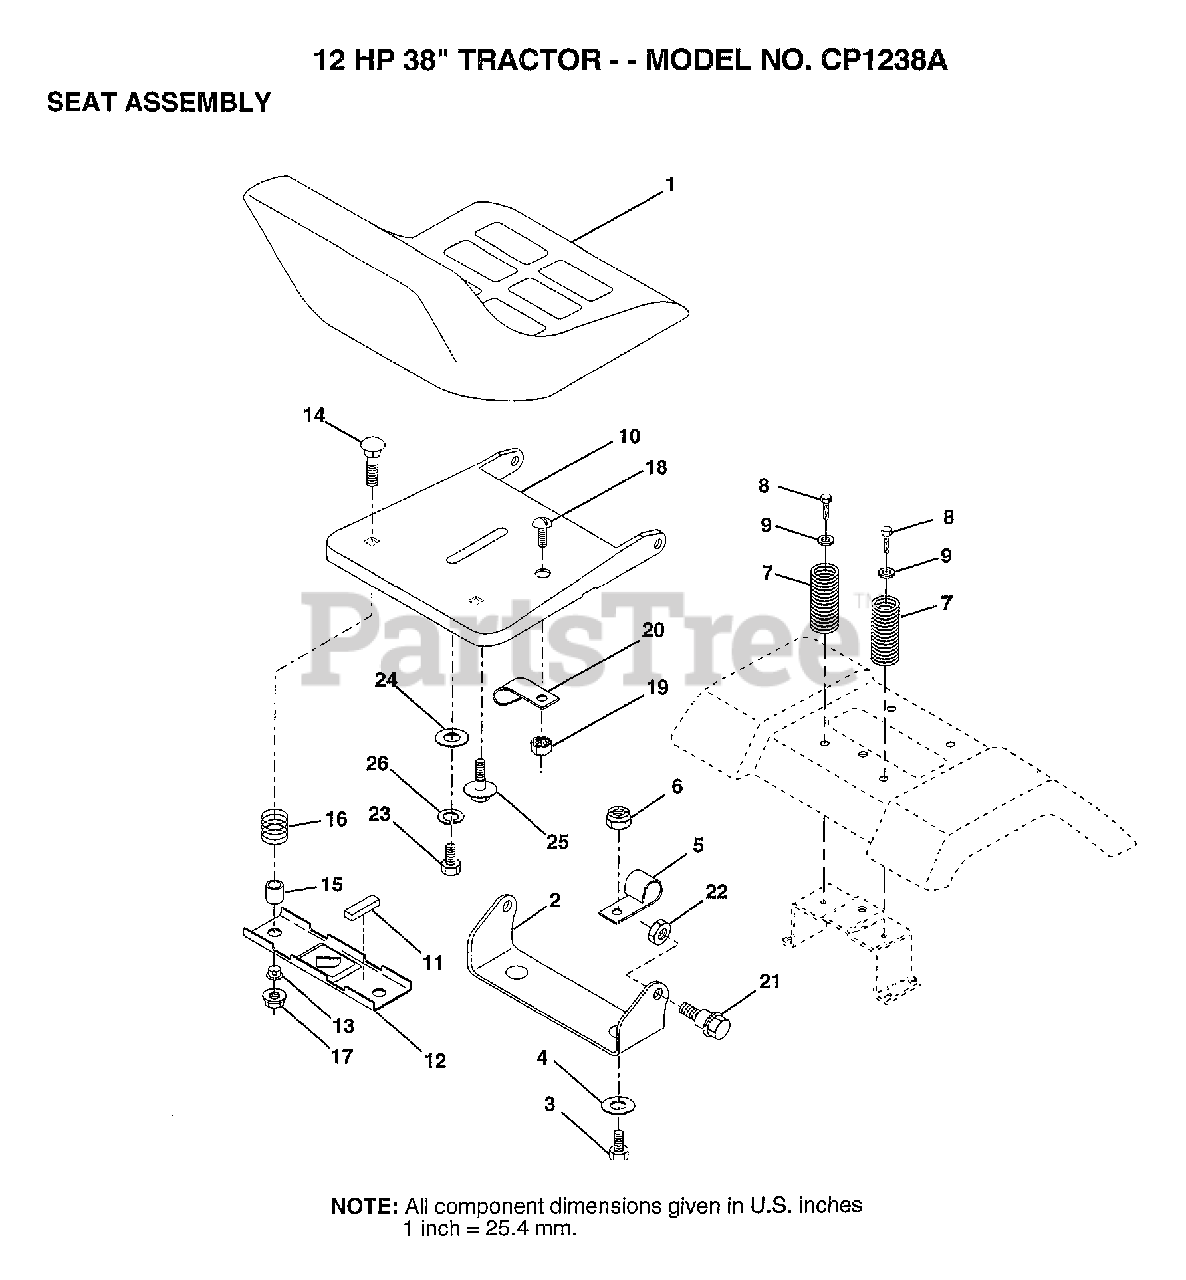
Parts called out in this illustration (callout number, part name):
4	WASHER PM
5	CLIP T
7	SPRING COMPRESSIO
8	SCREW GTV
9	WASHER
11	STRIP FORM
12	BRKT SWITCH
13	BUSHING
15	SPLIT SPACER
16	SPRING
19	"NUT,KEPS"
23	BOLT
24	WASHER
25	"BOLT,SHOULDER"
26	LOCKWASHER
